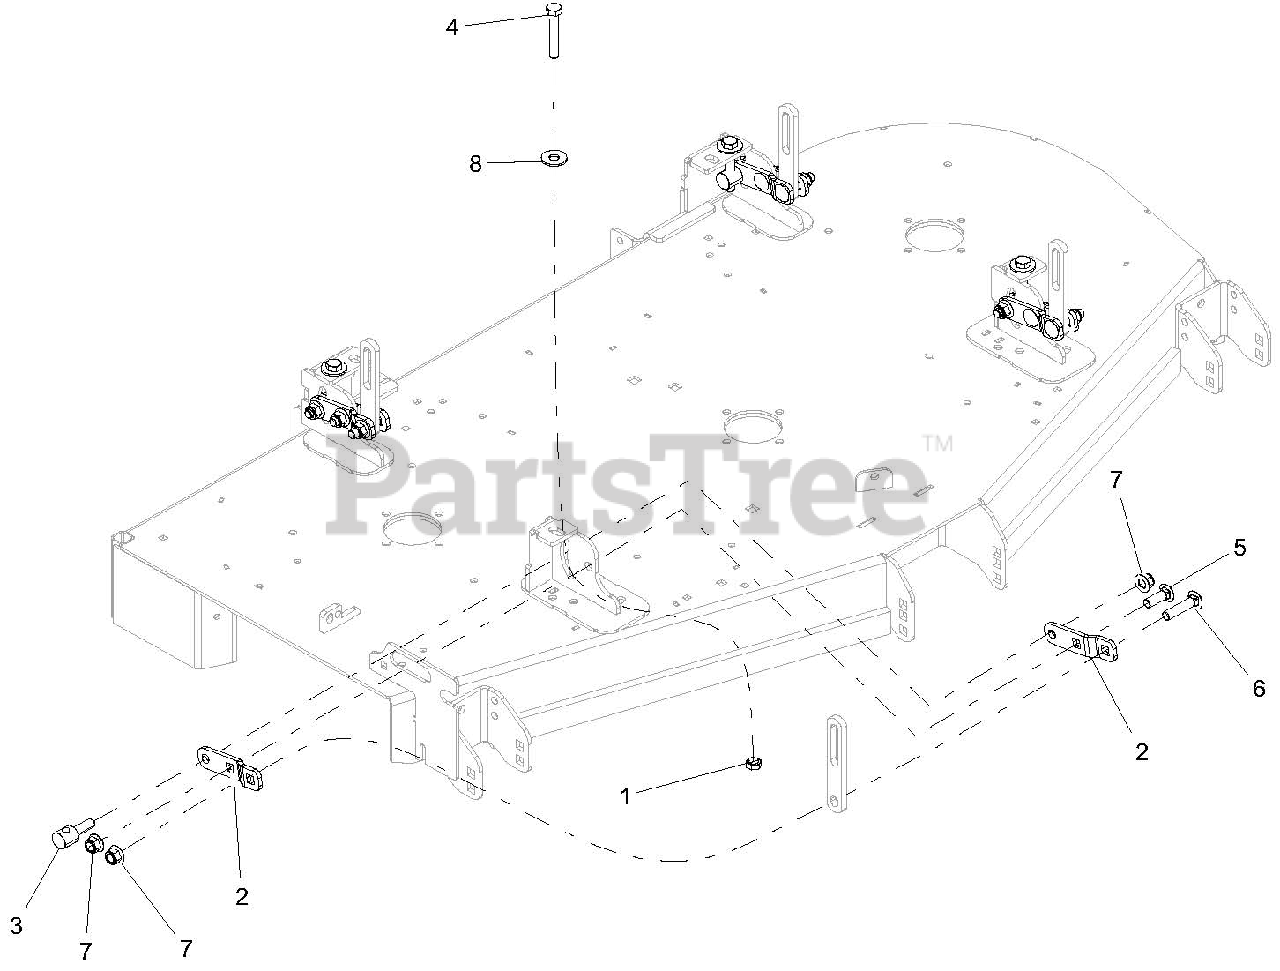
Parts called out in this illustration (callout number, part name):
1	NUT, JAM .500-13 YWZC
2	BRKT, DECK LEVELING-BLACK
3	TRUNNION, .50-13
4	BLT-HEX .50-13X3.00 GR5 FTH YWZC
5	BLT-RDHDSQNK .50-13X1.50 G5 YWZC
6	BLT-RDHDSQNK .50-13X2.25 G5 Y
7	NUT-LK-NYL-FLG .50-13 YWZC
8	WSHR-FL-STL.563X1.38X.109YWZC
